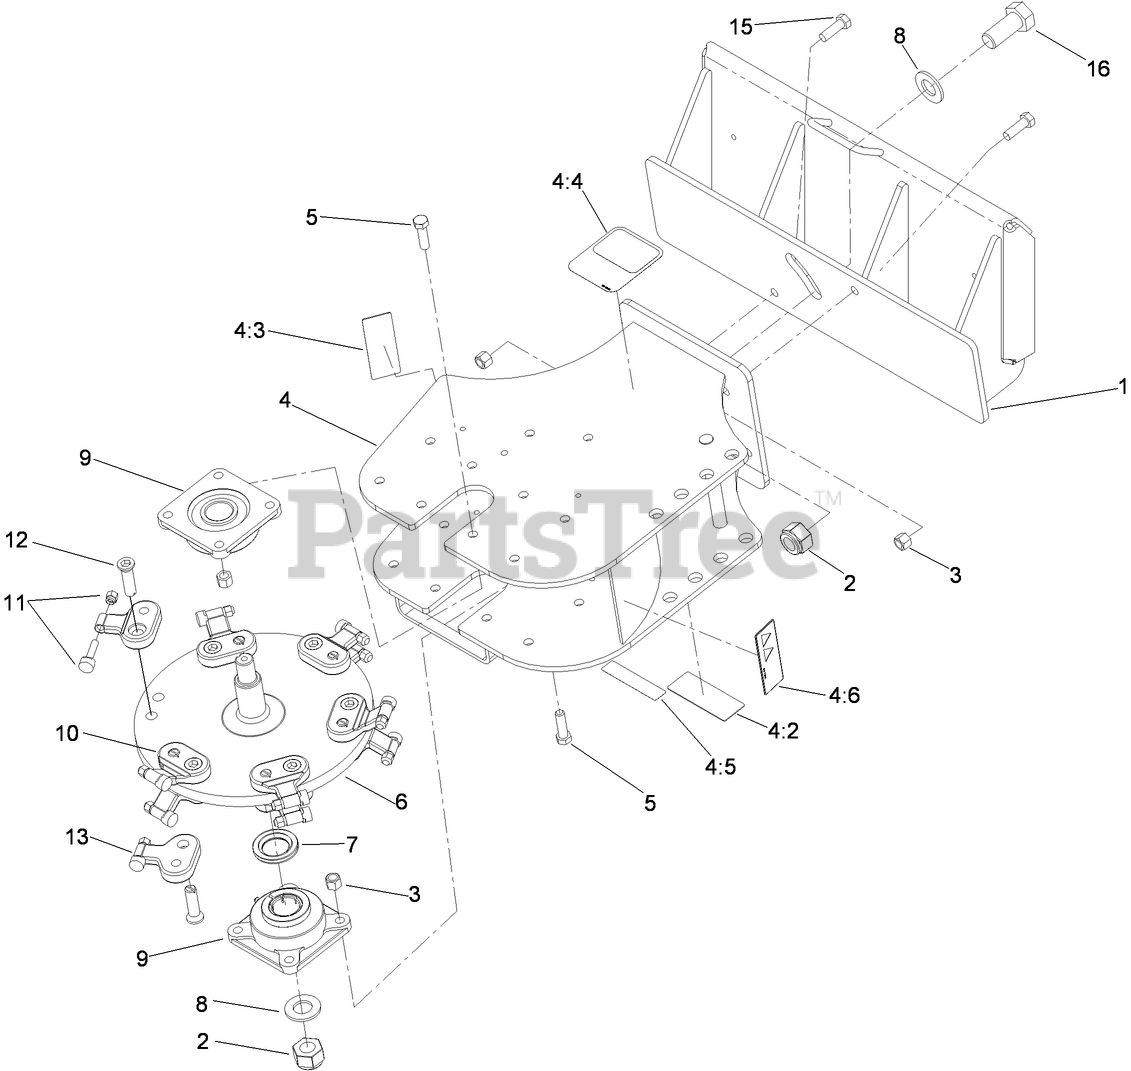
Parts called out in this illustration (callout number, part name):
1	QUICK ATTACH ASM
2	NUT-HEX, NI
3	NUT-LOCK, NI
4	GRINDER FRAME ASM
4:2	DECAL-WARNING
4:3	DECAL-DANGER
4:4	DECAL
4:5	DECAL-WARNING
4:6	DECAL-WARNING
5	SCREW-HH
6	WHEEL-CAST
7	WASHER-BEARING
8	WASHER-FLAT
9	BEARING
10	POCKET-ANGLED
11	GRINDER TOOTH ASM
12	BOLT-HSH, RH
13	POCKET-STRAIGHT
15	SCREW-HH
16	SCREW-CAP
